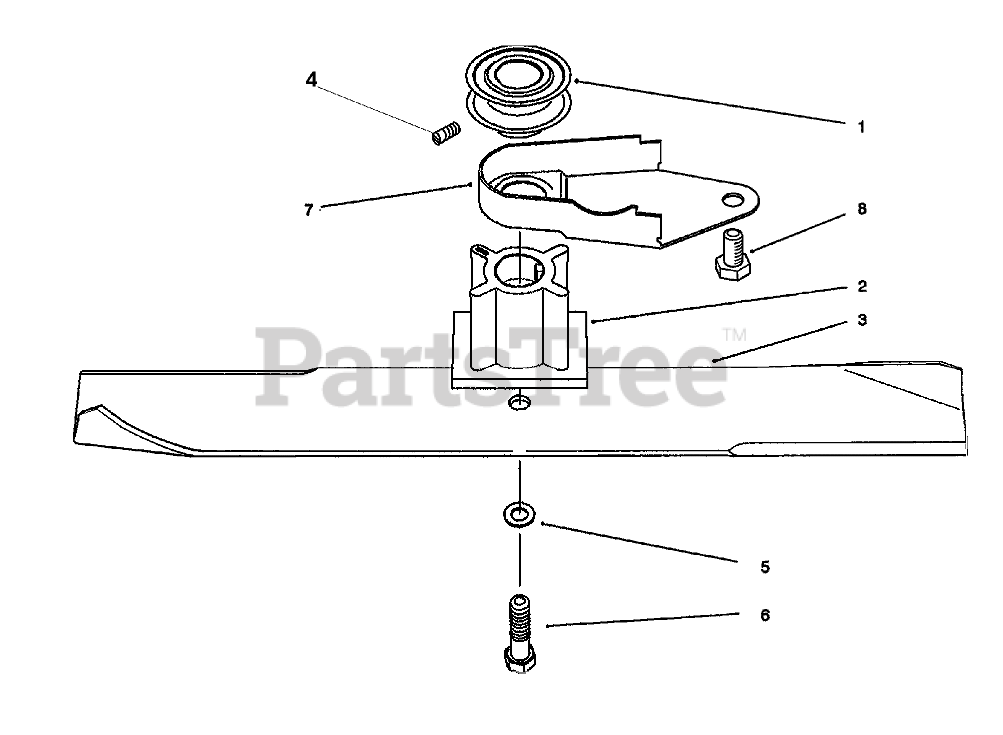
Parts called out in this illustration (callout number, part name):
1	Pulley-Driver
2	RETAINER-BLADE
3	BLADE-RECYLER
4	SCREW-WORM
5	WASHER-LOCK
6	BOLT-BLADE
7	COVER-GUIDE, BELT
8	SCREW-COVER, BELT
